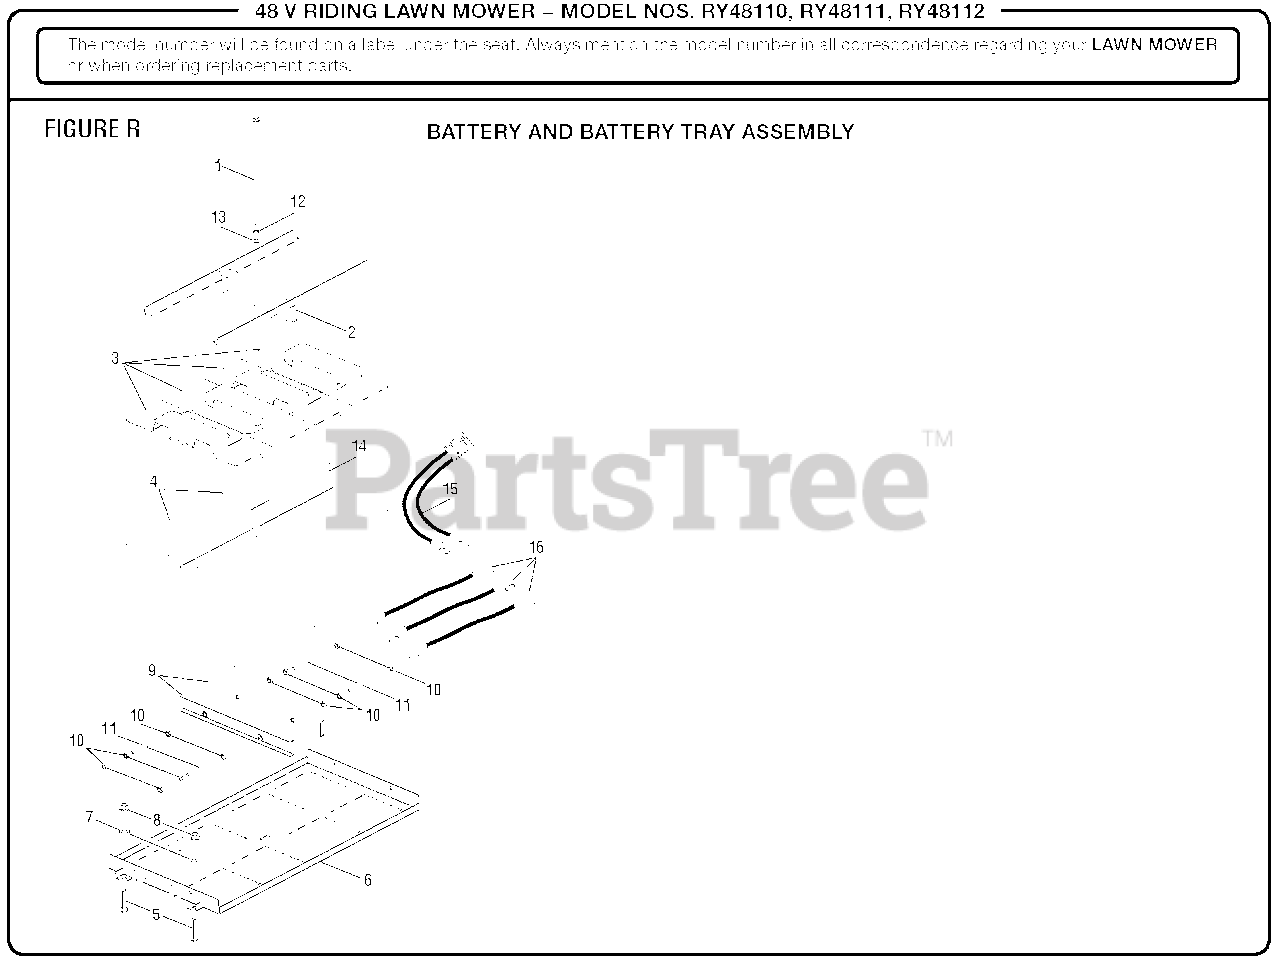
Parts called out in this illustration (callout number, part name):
1	Bolt (M8)
2	Battery Tie Down
3	Battery Cover
4	Battery (LPC12-75, RY48110, RY48112)
4	Battery (LPC12-100, RY48111)
5	Flange Bolt (M8 x 55 mm, Hex Hd.)
6	Battery Tray
7	Metal Bushing
8	Flange Nut (M8)
9	Battery Holder Bracket
10	Hex Nut (M8)
11	Threaded Rod (M8 x 100 mm)
12	Lock Washer (OD9.8 x ID8.5 x 5t)
13	Washer (OD12.5 x ID8.4 x 4t)
14	Battery Spacer (LPC12-75)
15	Two Wire Battery Cable (4 AWG Black & 4 AWG Red, 250 mm)
16	Battery Cable w/Covers (Red and Black, 120 mm)
